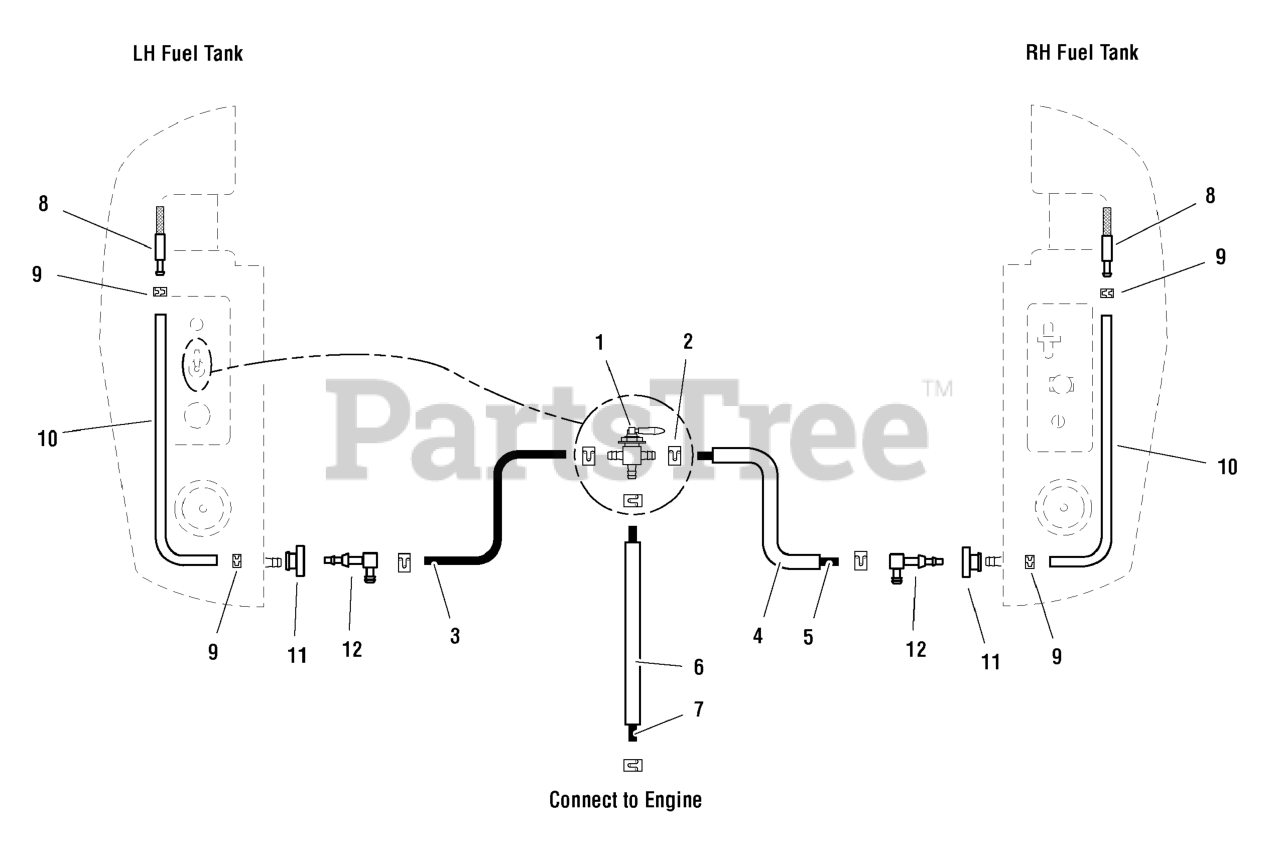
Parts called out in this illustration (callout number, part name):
1	VALVE, Fuel Shut Off
2	CLAMP, Hose
3	1/4" Fuel Line, 7-1/2" Long
4	WIRE LOOM, 34"
5	1/4" Fuel Line, 36" Long
6	WIRE LOOM, 46"
7	1/4" Fuel Line, 48" Long
8	SEE HOSE ASSEMBLY
9	SEE HOSE ASSEMBLY
10	ASSM, FUEL HOSE, 26
11	BUSHING-FUEL TANK RED RUBBER
12	ELBOW FITTING
